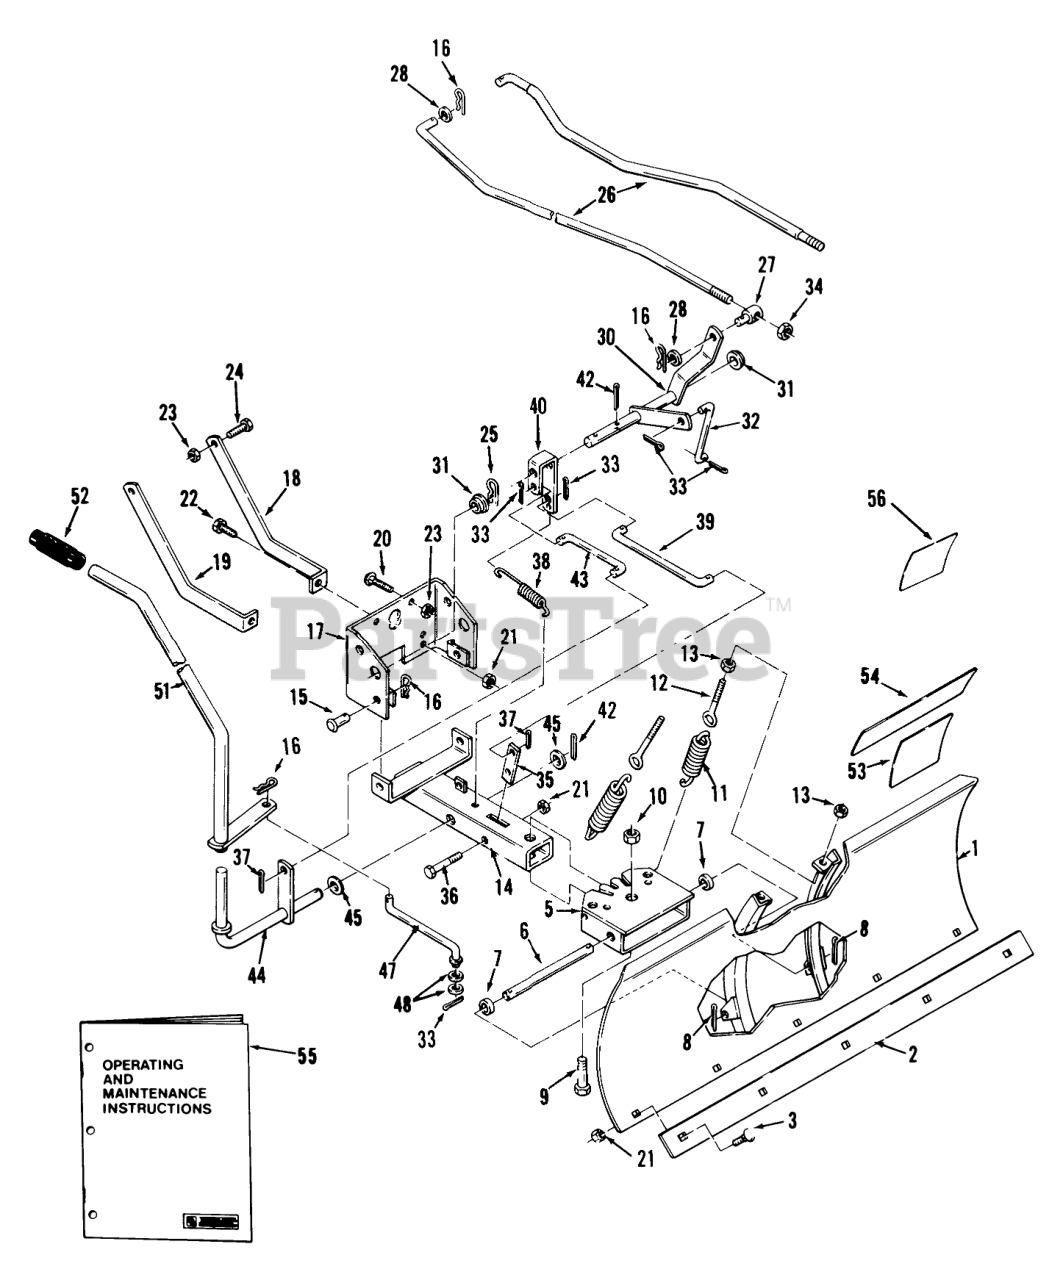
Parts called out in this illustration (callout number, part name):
1	Blade
2	Plate
3	Bolt-Carriage
5	ASS'Y-QUADRANT R
6	ROD-LOWER
7	Spacer
9	HEX HD CAP SCREW
10	Nut
11	SPRING
12	EYEBOLT
13	Nut
14	ASS'Y-FRAME R
15	CLEVIS PIN
16	Hairpin Cotter
17	ASSY-FRONT SUPPOR R
18	BRACE-FRAME MT LH R
19	BRACE-FRAME MT RH R
20	Bolt-Carriage
21	NUT
22	BOLT
23	Nut
24	Bolt
25	Hairpin
26	ROD-LIFT B
27	TRUNION
28	Washer
30	Bellcrank Lift
31	BUSHING
32	ROD-LIFT R
33	Pop Rivet
34	Nut
35	Latch
36	HHCS
38	SPRING
39	ROD-LATCH
40	BELLCRANK-LATCH R
42	Cotter Pin
43	ROD-BELLCRANK
44	ASS'Y-HANDLE PIVO R
45	Washer
47	ROD-ANGLING
48	Washer
51	ASSY-HANDLE R
52	HANDGRIP
53	DECAL-DANGER
54	Decal
55	Operating and Maintenance Instructions
56	DECAL-OVERLAY
